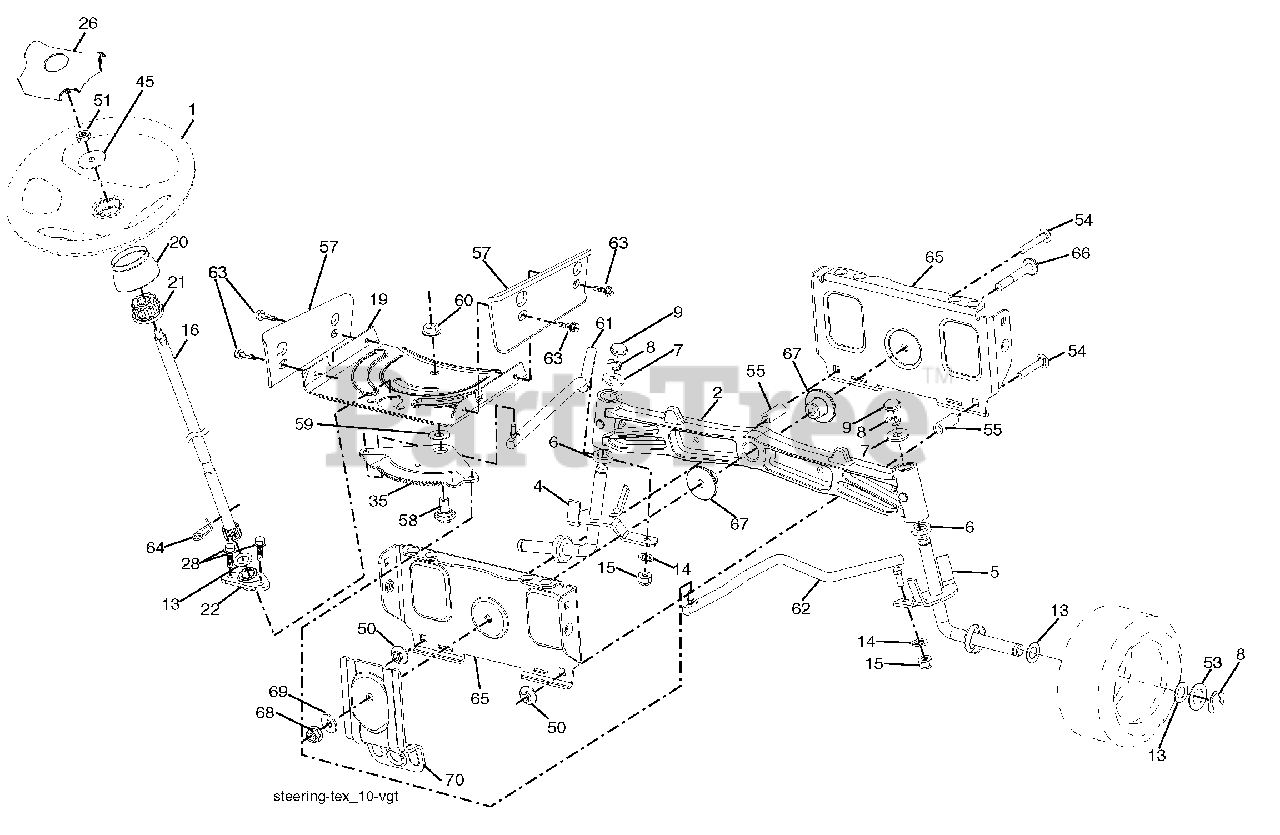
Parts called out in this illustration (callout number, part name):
1	Wheel, Steering
2	Axle Asm., Front
4	Spindle Asm., LH
5	Spindle Asm., RH
6	Bearing, Race Thrust Harden
7	Washer 25/32 x 1-5/8 x 16 Ga.
8	Ring, Klip #T5304-75
9	Cap, Spindle
13	Washer 25/32 x 1-1/4 x 16 Ga.
14	Washer Lock 3/8
15	Nut, Crown Lock 3/8-24 unf
16	Shaft Steering
19	Plate Steering
20	Boot, Steering
21	Adapter, Wheel Steering
22	Bushing, Strg. Blk
26	Insert, Wheel Steering
28	Screw 3/8-16 x 3/4
33	Washer Lock 5/16
35	Gear, Sector Plate
45	Washer 11/32 x 2-3/8 x 12 Ga.
50	Nut Lock Flg 3/8-16 unc
53	Washer Hardened .793 x 1.637 x .060
54	Bolt Hex HS 3/8-16 unc x 2-1/4
55	Spacer Brace Axle
57	Bracket Upstop
58	Bolt Shoulder Sector Pivot CFM
59	Washer Thrust Sector Steering
60	Nut Flange Lock 5/8-11
61	Draglink LH
62	Draglink, RH
63	Screw 5/16-18 x 3/4
64	Retainer Clip Spring Steering
65	Brace Axle Front
66	Bolt Hex Fghd 7/16-14 x 3 Serr
67	Bushing PM Front Axle
68	Nut Lock Flange 7/16-14 Gr. 5
69	Washer 1.5 x .505 x .118
70	Bracket Deck Susp. Front
71	Shaft Ext. Steering
72	Bolt 5/16-18 x 4.5 Gr. 5
